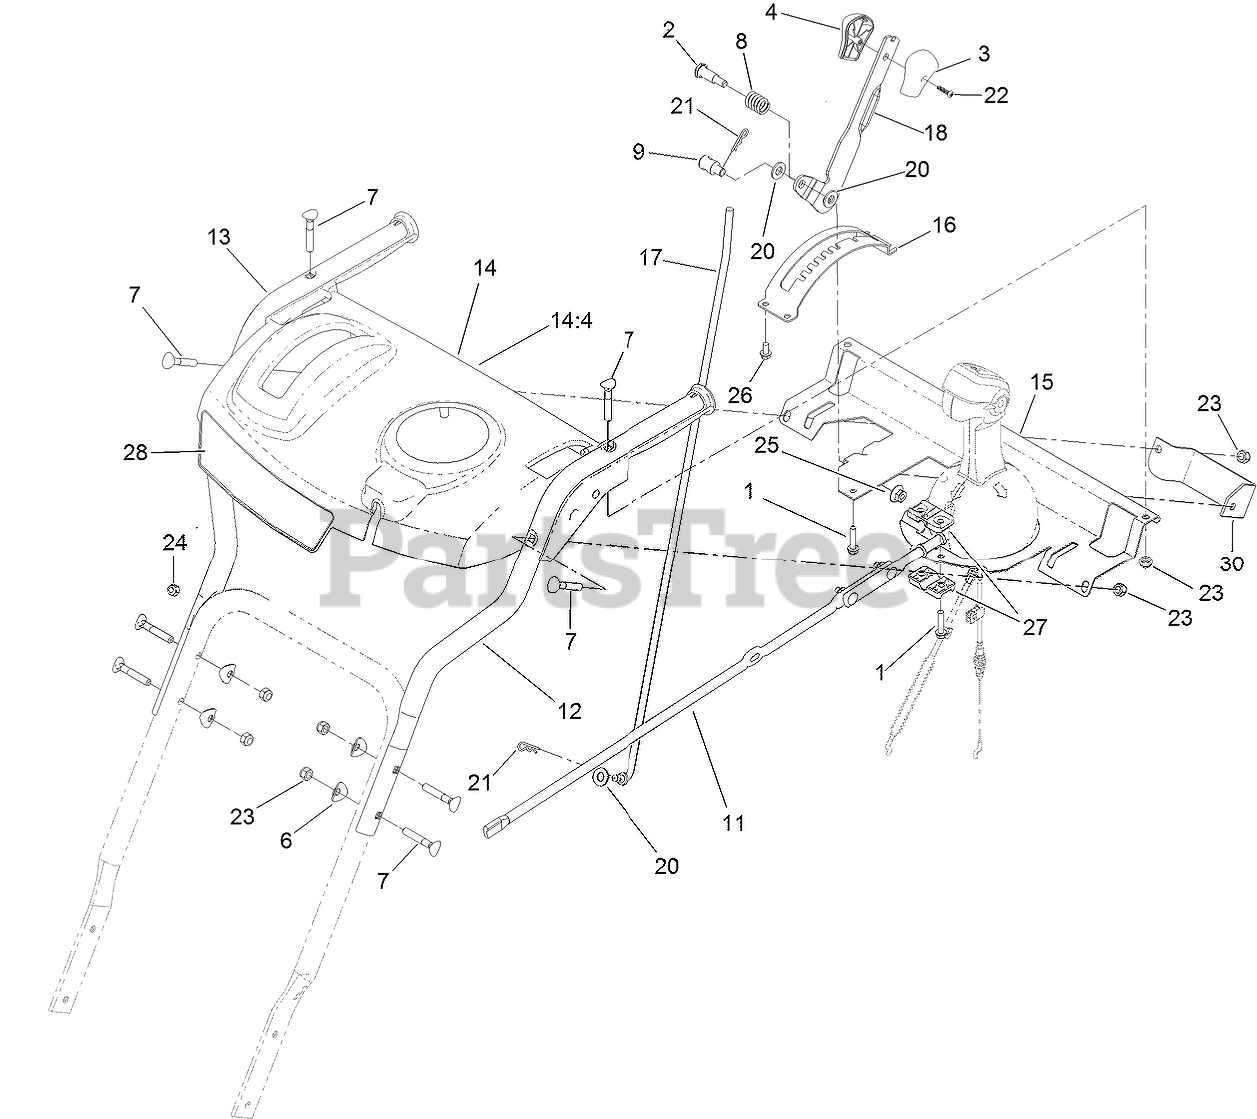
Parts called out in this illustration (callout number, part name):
1	SCREW-PLASTITE, HWH
2	SCREW-SHOULDER, HH
3	KNOB-SHIFT, LH
4	KNOB-SHIFT, RH
6	WASHER-CUP
7	SCREW-HANDLE
8	SPRING-COMPRESSION
9	TRUNNION-ROD
11	ROD-CHUTE
12	HANDLE-UPPER, LH
13	HANDLE-UPPER, RH
14	CONTROL PANEL ASM
14:4	DECAL-SAFETY
15	SUPPORT-PANEL, CONTROL
16	MOUNT-SELECTOR, SPEED
17	ROD-SELECTOR, GEAR
18	SELECTOR-SPEED
20	WASHER-THRUST
21	PIN-HAIR
22	SCREW-PPH
23	NUT-HEX
24	NUT-HEX
25	NUT-HF
26	SCREW-PLASTITE
27	SUPPORT-ROD
30	PLATE-SUPPORT, SHIFT
